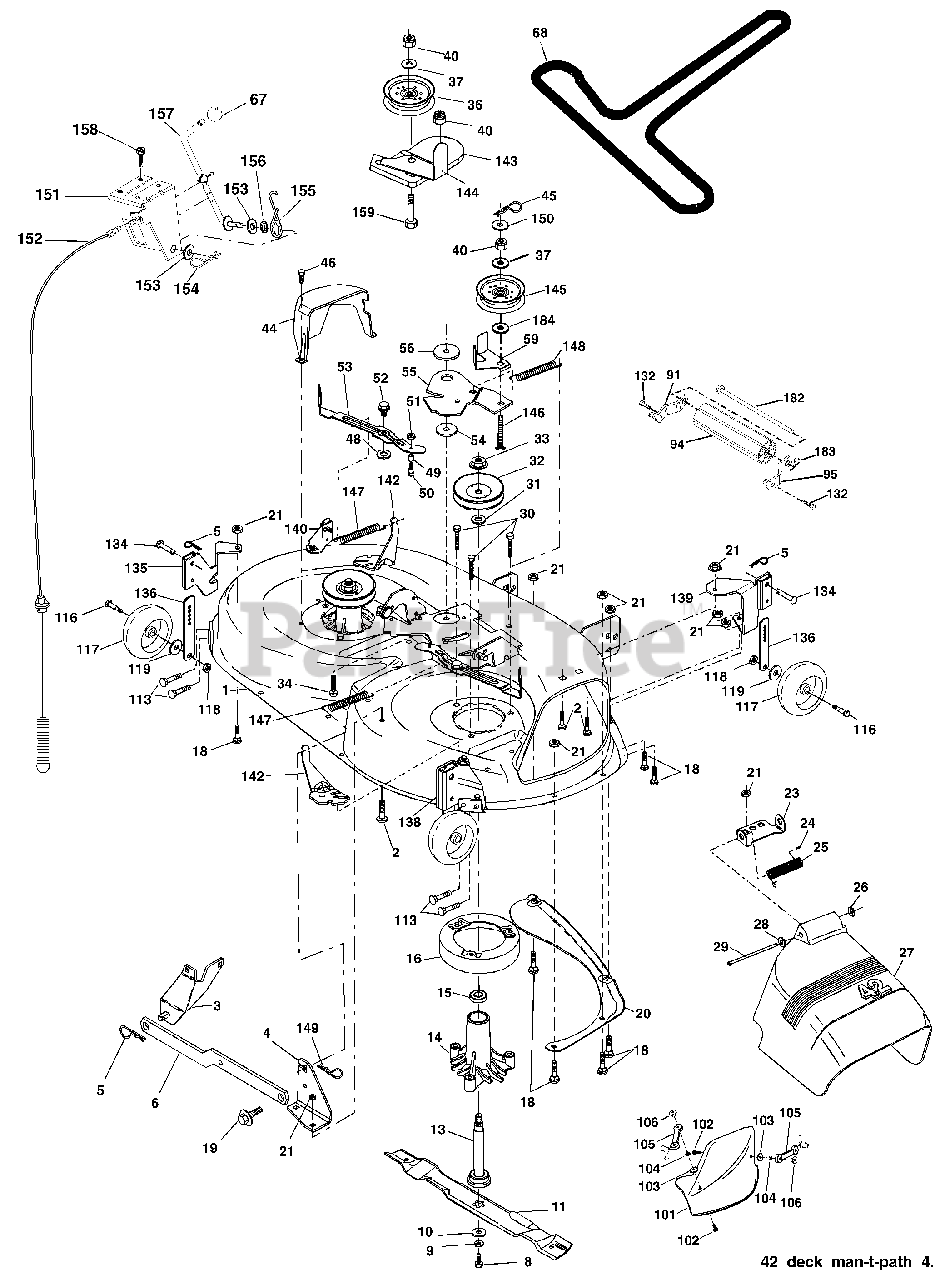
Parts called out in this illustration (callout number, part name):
1	Mower Deck Assembly, 42"
2	Bolt
3	Bracket Asm Fr. Sway Bar 3/42
4	Bracket Asm Deck 42" Sway Bar
5	Retainer Spring
6	Bar Sway Deck
8	Bolt 3/8-24 x 25 Grade 8 patched
9	Washer, Lock
10	Washer, Hardened
11	Blade, 42" Mulching Std
11	Blade, 42" Mulching Premium
11	Blade, 42" Hi-Lift
13	Shaft Assembly, Mandrel, Vented
14	Housing, Mandrel, Vented
15	Bearing, Ball, Mandrel
16	Stripper, Vented Mower Deck
18	Bolt, Carriage 5/16-18 x 5/8
19	Bolt, Shoulder
20	Baffle, Vortex
21	Nut
23	Bracket, Deflector Mower 42"
24	Cap, Sleeve 80 x 112 Blk Mower
25	Spring, Torsion, Deflector 2 52
26	Nut, Push Phos & Oil
27	Shield, Deflector 42" Blk
28	Washer 11/32 x 5/8 x 16 Gauge
29	Rod, Hinge 42" 6 75 W/G
30	Screw Thdrol Washer Head
31	Washer, Spacer Mower Vented
32	Pulley, Mandrel
33	Nut, Toplock Flange
34	Bolt
36	Pulley, Idler, Flat
37	Washer 13/32 x 13/16 x 16 Gauge
40	Nut
44	Guard, Mandrel, LH
45	Retainer
46	Screw, Thdrol 1/4-20 x 5/8 T
48	Washer, Hardened
49	Roller Assembly, Cam Follower
50	Bolt, Shoulder #10-24 Grade 5
51	Locknut
52	Bolt, Shoulder 5/16-18 UNC
53	Arm Assembly, Pad, Brake
54	Washer, Hardened
55	Arm, Idler
56	Spacer, Retainer
59	Guard TUV Idler
67	Knob
68	V-Belt, 42" Mower
91	Bracket Noseroller LH
94	Roller Nose
95	Bracket Noseroller RH
101	Cover Mulching
102	Screw 10-24 x 5/8
103	Washer #10
104	Washer Lock #10
105	Latch Asm.
106	Nut Weld
113	Screw 5/16-18 x 3/4
116	Bolt Shoulder 3/8-16 x 3-5/8
117	Wheel Gauge
118	Nut 3/8-16
119	Washer 3/8 x 7/8 x 14 Ga.
132	Screw 3/8-16 x 3/4
134	Pin Head Rivet
135	Bracket Asm. LH Rear
136	Bar Adjusting
138	Bracket Asm. RH Rear
139	Bracket Asm. RH Front
140	Bracket Asm. LH Front
142	Arm Spring Brake Mower
143	Bracket Arm Idler 42"
144	Keeper Belt 42" Clutch Cable
145	Pulley Idler Flat
146	Bolt Carriage Idler
147	Spring Extension
148	Spring Return Idler
149	Retainer Spring Yellow
150	Washer 9/32 x 3/4 x 16 Ga.
151	Bracket Clutch Cable
152	Clutch Cable 42"
153	Washer Flat 3/8" Type B
154	Spring Retainer
155	Spring Retention LVR CLTCH CAB
156	Spacer Clutch Cable
157	Rod Clutch Cable 3/8"
158	Screw Hex Thd Cut 1/4-20 x 1/2
159	Bolt Rdhd Sqn 3/8-16 UNC x 1-3/4
182	Rod Roller Nose
183	Retainer Spring
184	Washer 13/32 x 7/8 x 10 Ga.
